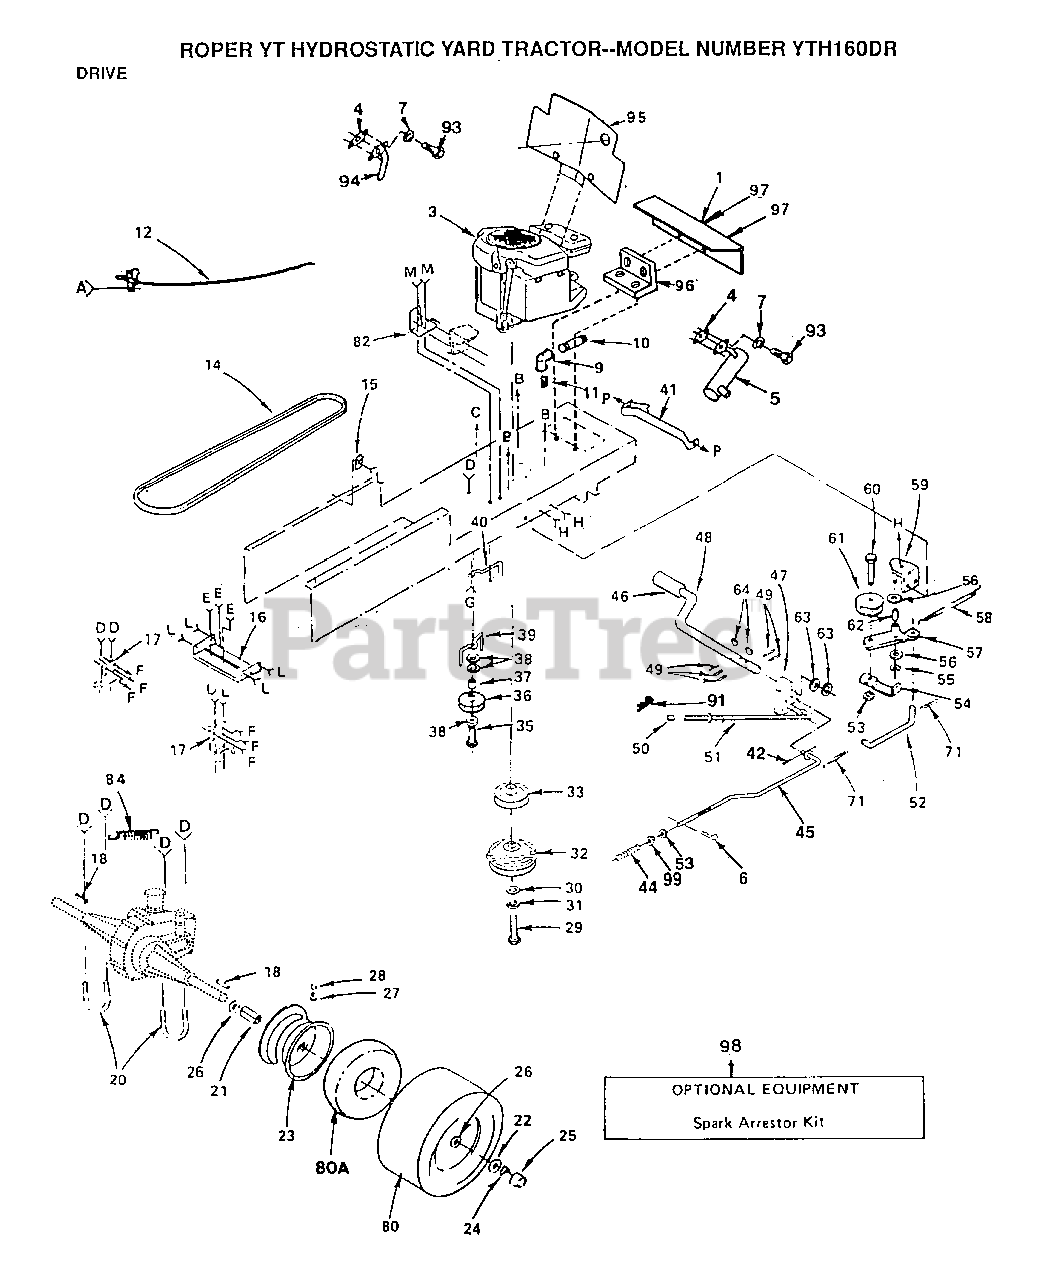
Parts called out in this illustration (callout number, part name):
1	BAFFLE - VERTICAL
3	ENGINE 16 H.P. MODEL #402707 TYPE #1211 - 01
6	RETAINER M
7	LOCKWASHER
9	ELBOW
10	PIPE NIPPLE LT
11	PLUG OIL DRAIN
12	CONTROL THROTTLE
15	CLIP T
16	PLATE TRANS SUPT
20	U BOLT
21	SPACER SPLIT
22	WASHER
24	E-RING LT
25	HUB CAP
27	VALVE STEM LT
28	VALVE CAP
30	WASHER LT
31	LOCKWASHER
35	BOLT
37	SPACER T
38	WASHER
39	"KEEPER,BLT ENG LT"
40	KEEPER BELT ENGLH
42	COTTER PIN
44	SPRING ROD LT
45	ROD BRAKE
46	PEDAL COVER T
47	ARM BRAKE LT
48	SHAFT, FOOT PEDAL
49	LOCKWASHER
50	PLUNGER CAP T
52	"LINK, CLUTCH T"
55	KLIP RING
56	WASHER LT
57	"ASS T, BELLCRAN"
58	"SPRING, RETURN LT"
62	"LY, BEARING"
63	WASHER
71	COTTER PIN
80A	TUBE.18X9.5-8
82	BRACKET LT
91	SPRING.RETAINER
94	EXHAUST TUBE T
96	BRACKET HEAT SHIELD
97	SCREW LT
99	NUT
